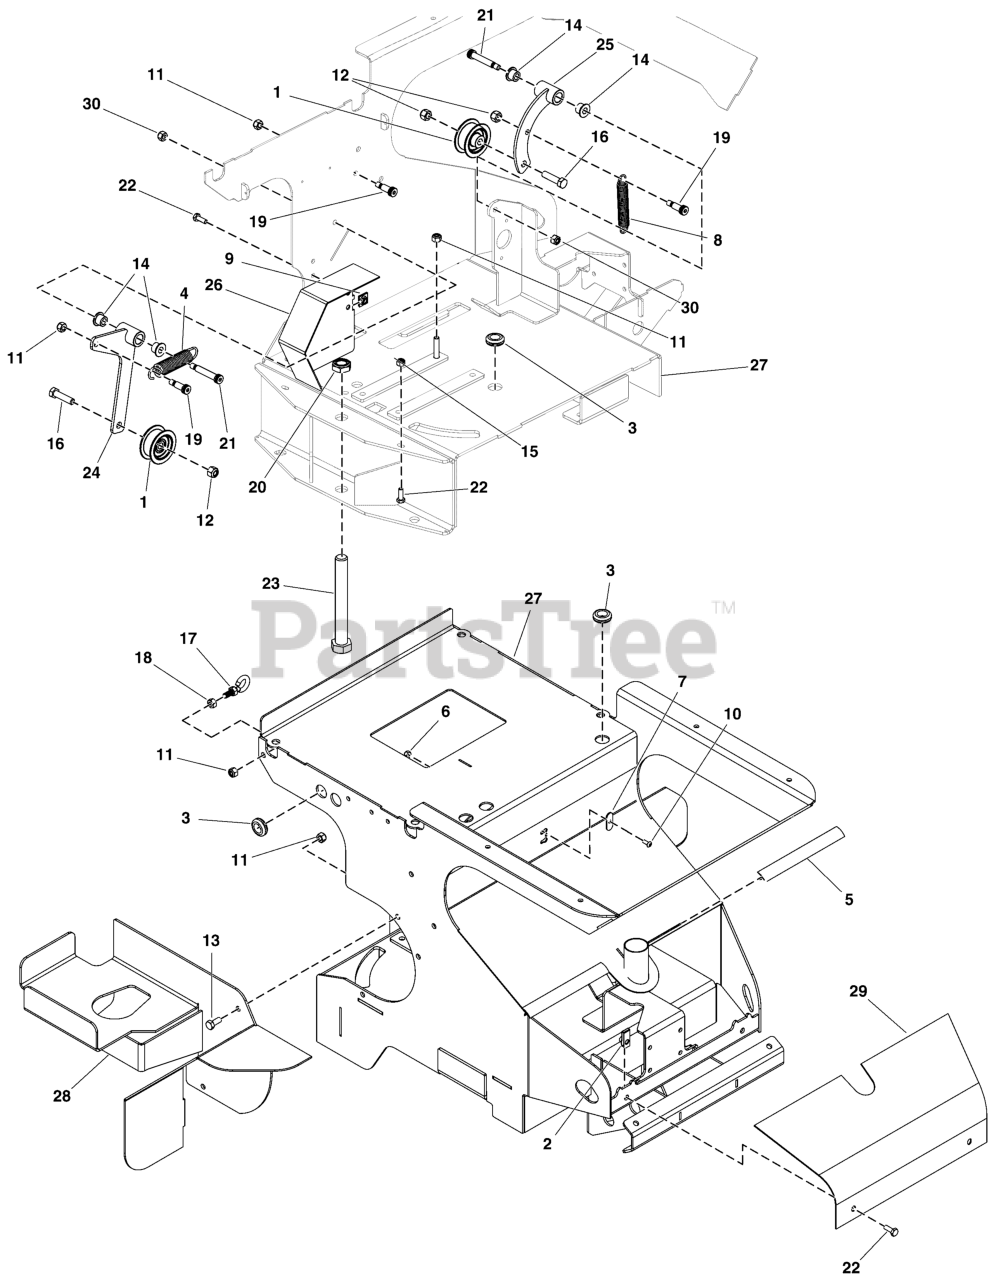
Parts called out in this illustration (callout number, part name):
1	PULLEY IDLER 1.75" OD X 3/8" BORE
2	NUT-CLIP .250"-20 X .781" EDGE DISTANCE
3	GROMMET, .875" HOLE X .625" ID X .125 GROOVE
4	SPRING, EXTENSION .840" OD X 4.00" LONG SS
5	SEAL TRIM, FRONT COWL 6.820" LONG
6	NUT-HEX-NYLK, #10-24 SS188
7	PLATE, CABLE HOLDER
8	SPRING, EXTENSION .64" OD X 4.00" LG SS
9	NUT-CLIP, .250"-20 X .375" EDGE DISTANCE
10	SCR-CAP, BSH #10-24 X .500" SS188
11	NUT-HEX-NYLK, 0.3125"-18 SS188
12	NUT-HEX-NYLK, .375"-16 SS188
13	SCR-CAP, HEX .3125"-18 X .750" SS188
14	BSHG-FL, .500" X .625" X .500", .875"x .062" IR
15	NUT-HEX-NYLK, .250"-20 SS188
16	SCR-CAP, HEX .375"-16 X 1.500" SS188
17	BOLT EYE, .3125"-18 X 1.000" SS188
18	NUT-HEX, .3125"-18 SS188
19	BLT-SLDR, SH .38"X0.75,.313-18 X.50 SS
20	NUT-HEX-NYLK, .750"-10 TH GA ZP
21	BLT-SLDR,SH.50"X1.25",.375"-16X.63"SS188
22	SCR-CAP, HEX .250"-20 X .750" SS188
23	SCR-CAP, HEX .750"-10 X 6.000" SS188
24	ASSY, IDLER ARM, LARGE PATH (S0108)
24	WELD, ARM IDLER PATHFINDER
25	WELD, ARM, SMALL IDLER
26	WELD, COVER, PULLEY
27	WELD, FRAME
28	WELD, FUEL TANK MOUNT
29	PANEL, FRONT COWL
30	NUT-HEX-NYLK, FLG .375"-16 SS188
